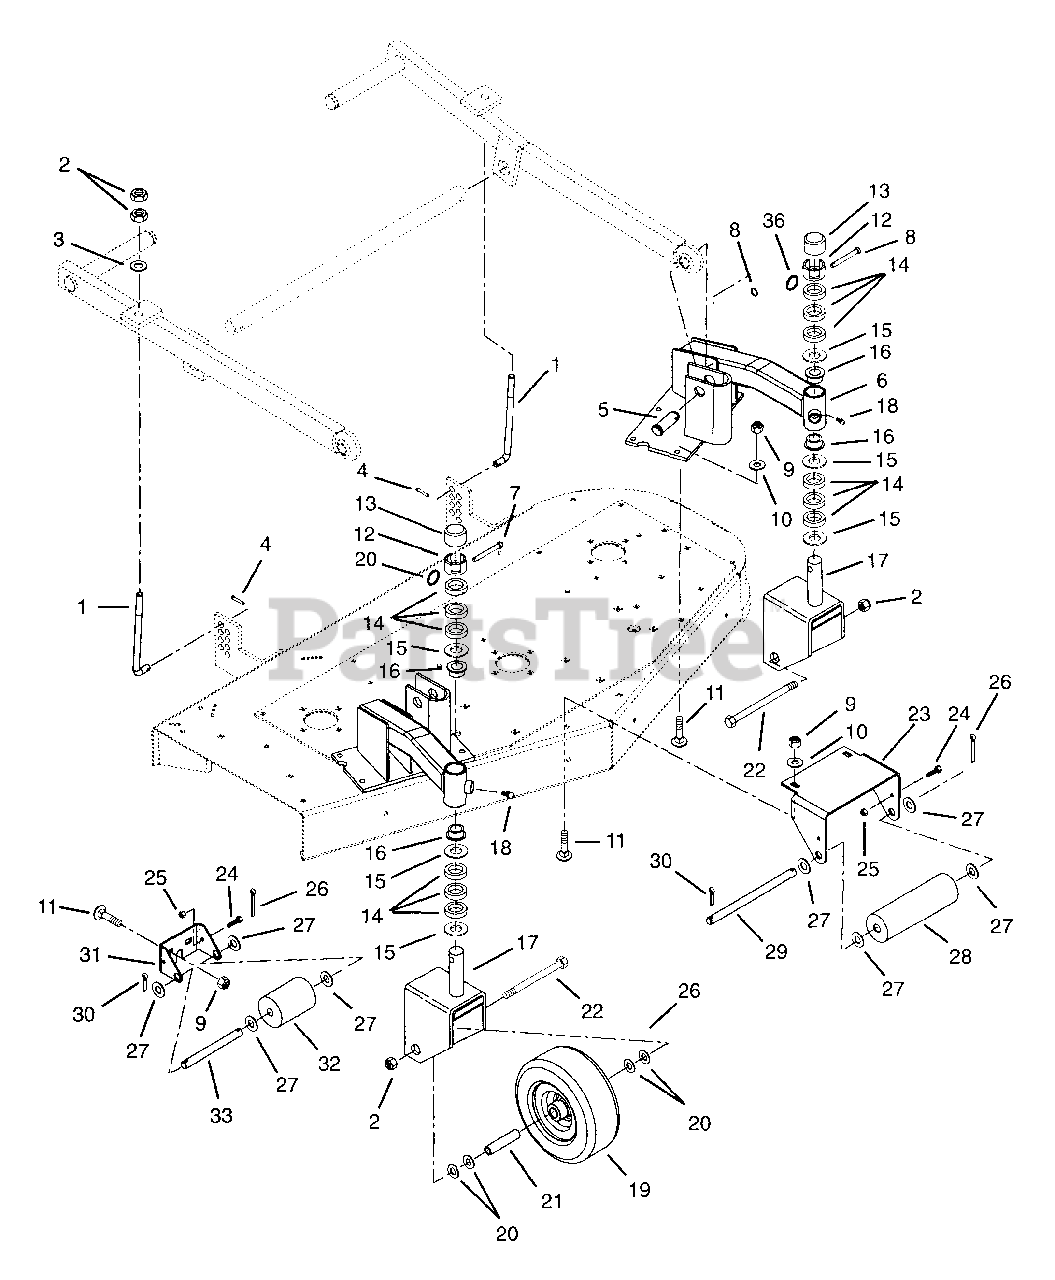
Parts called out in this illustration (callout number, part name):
1	Rod, Rear Height Adjustment
2	Nut-Locking-Nylon .50-13 Grade 5
3	Washer-Flat-Steel .50 x 1.25 x .083
4	Pin-Klik 1.00 x .188 x 1.25
5	Pin-Clevis .875 x 3.00
6	Weldment, Lift Arm Mount Left Hand
7	Pin-Clevis .309 x 1.25
8	Ring-Retaining-External 2.240 x .180
9	Nut-Locking-Nylon .38-16
10	Washer-Flat-Steel .406 x .812 x .065
11	Bolt-Round Head Square Neck .38-16 x 1.00
12	Spindle Cup
13	Cap, Hub
14	Bushing-Sleeve 1.04 x 1.75 x .500
15	Washer-Hardened-Thrust 1.00 x 1.55 x .03
16	Bushing-Flange 1.020 x 1.385 x .75 x 1.75
17	Weldment, Caster Fork
18	Fitting-Lube .25-28 x .256
19	Kit, Pneumatic Tire Replacement
20	Washer-Flat-Steel .50 x 1.25 x .083
21	Spacer .532 x .748 x 3.34
22	Bolt-Hex .50-13 x 5.50 Grade 5
23	Bracket, Gauge Roller
24	Bolt-Hex .25-20 x .75 Grade 5
25	Nut-Locking-Nylon .25-20
26	Pin-Cotter .250 x 2.00
27	Washer-Flat-Steel .656 x 1.312 x .095
28	Roller, Gage
29	Shaft, Center Roller
30	Pin-Cotter .25 x 1.00
31	Bracket, Roller
32	Roller, Gauge
33	Rod
34	Weldment, Lift Arm Mount Right Hand
36	Ring-Retaining-External 1.062 x 1.25
